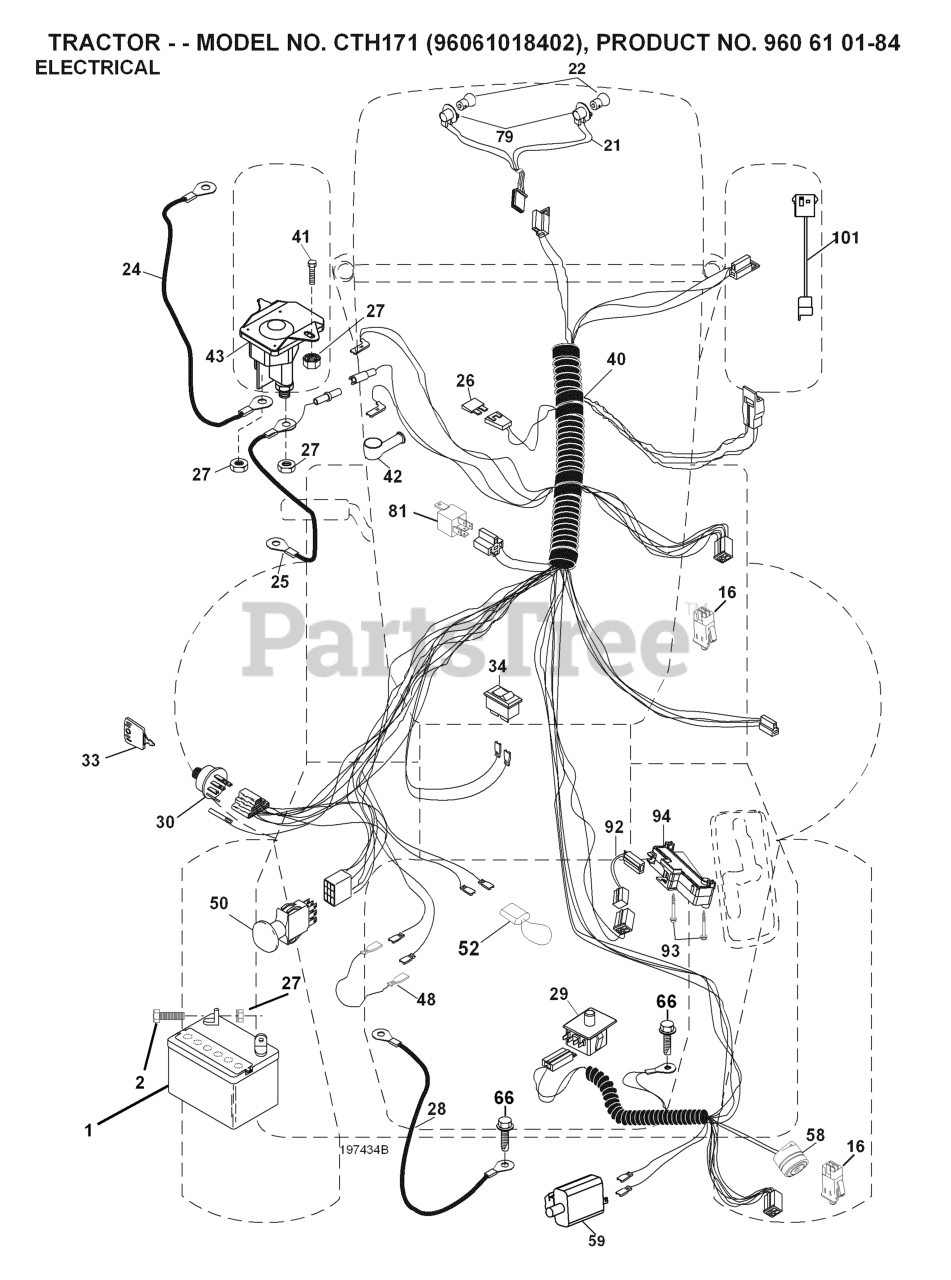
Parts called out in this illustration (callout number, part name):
1	BATTERY 12V .35 AMP
2	BOLT.HEX.1/4.X.3/4.DICHROMATE
16	SWITCH INTERLOOK PUSH-IN
21	HARNESS.LIGHT W/4152J BULBS
24	BATTERY CABLE GT
25	CABLE BATTERY
26	FUSE 20AMP
27	NUT
28	CABLE GROUND
29	SWITCH.SEAT.DP W/RAMPS
30	SWITCH.IGN.DELTA.W.LGH.ROS
33	KEY MLD GEN DELTA
40	RP HARNESS.IGN.ELECT.REG.CRD
41	BOLT
42	TERMINAL COVER
43	SOLENOID.W/BRASS.PLUNGER
48	ADAPTER.AMMETER
50	RP.PTO.SWITCH.8 TERMINAL.BLACK
58	BUZZER
59	.WITCH.FULL BAGGER.INDICATOR
66	SCREW LT
79	BULB HOLDER ASM.
81	RELAY.ASSY.T
92	HARNESS.PIGTAIL.CONSLE
93	SCREW.PLASTITE
94	MODULE.REVERSE.ROS
101	PIGTAIL.MATNLK.NEW.HAR
